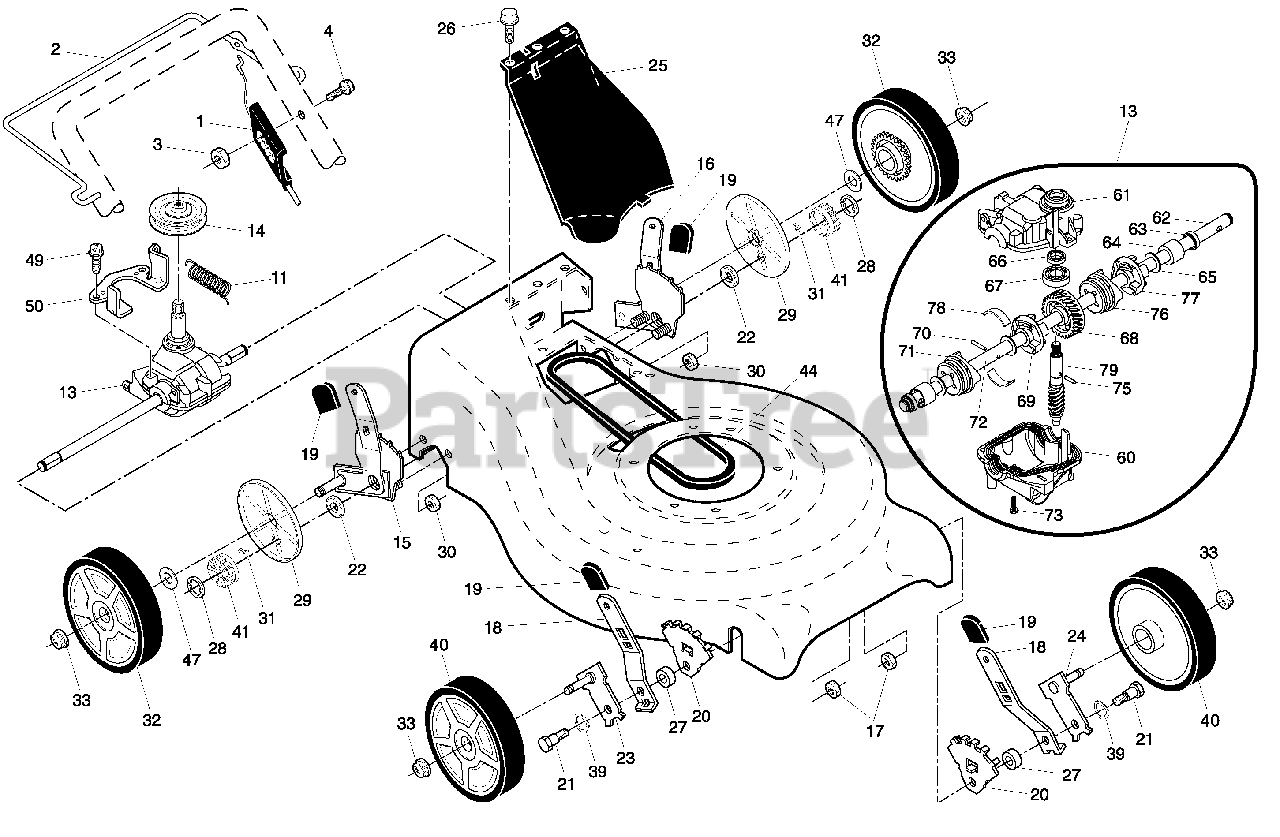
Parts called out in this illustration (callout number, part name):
1	Drive Control Assembly
2	Lever, Drive Control
3	Nut, Hex
4	Screw
11	Spring, Return
13	Gear Case Assembly, Complete
14	Pulley, Drive
15	Kit, Wheel Adjuster Assembly, RH
16	Kit, Wheel Adjuster Assembly, LH
17	Nut, Hex
18	Spring, Selector
19	Knob, Selector Spring
20	Bracket, Wheel Adjusting
21	Bolt, Shoulder, Hex Head
22	Bearing, Ball
23	Axle Arm Assembly, RH
24	Axle Arm Assembly, LH
25	Cover Drive
26	Screw, Threaded, Rolled #10-25 x .50
27	Spacer
28	E-Ring 7/16
29	Cover, Dust, Wheel
30	Nut, Hex
31	Pawl, Drive
32	Wheel & Tire Assembly, Rear 8 x 1-3/4
33	Nut, Flangelock 3/8-16
34	Pinion
39	Washer, Curved, Cylindrical
40	Wheel & Tire Assembly, Front 8 x 1-3/4
44	V-Belt
47	Washer
49	Screw, Hi-Lo Thread #12 x 5/8
50	Belt Keeper
60	Case, Lower
61	Case, Upper
62	Shaft, Output, Long
63	Seal, Output Shaft
64	Bushing
65	Washer
66	Seal, Worm Shaft
67	Bearing, Ball
68	Gear, 28 Teeth
69	Movable Dog Clutch, LH
70	Pin, Output Shaft
71	Fixed Dog Clutch, LH
72	Shaft, Output, Short
73	Screw, Case
75	Pin, Worm Shaft
76	Movable Dog Clutch, RH
77	Fixed Dog Clutch, RH
78	Spring, Leaf
79	Shaft, Worm
